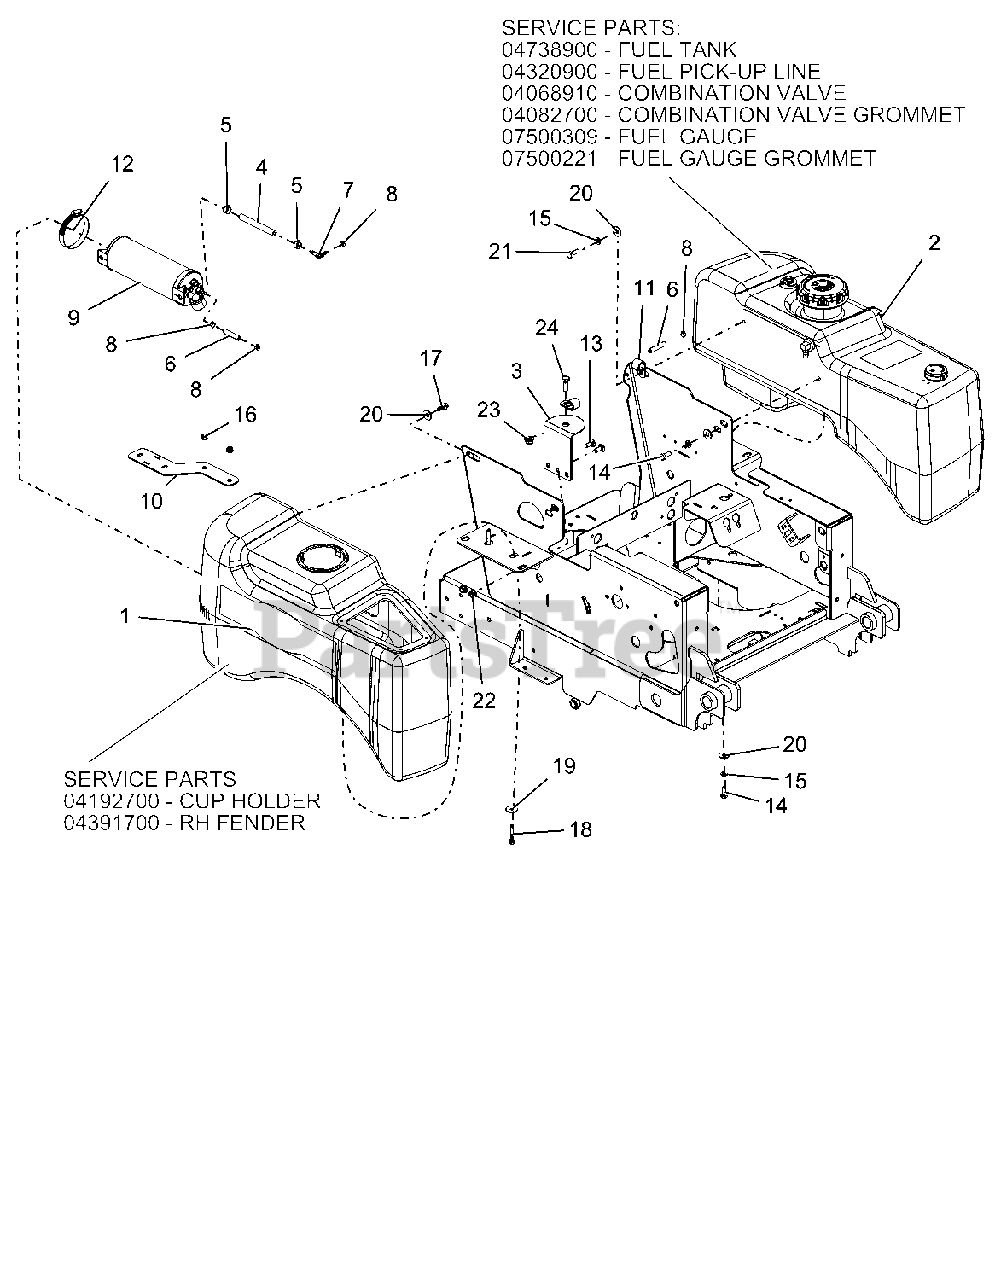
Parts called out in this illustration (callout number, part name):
1	CUP HOLDER
1	RH FENDER
1	ASM, FENDER W/CUPHOLDER
2	FUEL TANK
2	FUEL PICK-UP LINE
2	COMBINATION VALVE
2	COMBINATION VALVE GROMMET
2	FUEL GAUGE
2	FUEL GAUGE GROMMET
2	HD, FUEL TANK ASSEMBLY
3	BRKT, FUEL VALVE MTG - BLK
4	.25 LOW-PERM GAS HOSE 3.00" LG - TANK VENT TO CARBON CANISTER
5	CLAMP, FUEL LINE
6	.188 ID LOW-PERM X
7	FITTING-3/16X1/4 90DEGREE VAC
8	CLAMP - HOSE, SPRING .188
9	CANISTER, CARBON 9.3 GAL
10	PLATE, CANISTER MTG-BLACK
11	CLAMP, CUSHIONED STEEL .75
12	CLAMP, HOSE 2.3/3.2
13	BLT-RDHDSQNK .31-18X.75 G5 YWZC
14	BLT-HEX .31-18X.75 GR5 YWZC
15	WSHR-LK .31X.078 REG YWZC
16	NUT-LK-NYL-FLG .25-20 YWZC
17	SCR-PLASTITE .25-10X.75 YWZC
18	SCR-TAP .25-20X1.50 HWH TR YZ
19	WSHR-FL-STL .281X1.000X.063 YWZC
20	WSHR-FL-STL.38X.875X.083 YWZC
21	BLT-HEX .31-18X.875 GR5 YWZC
22	NUT-LK-NYL-FLG .31-18 YWZC
23	NUT-LK-NYL-FLG .38-16 YWZC
24	BLT-HEX .38-16X1.00 GR5 YWZC
